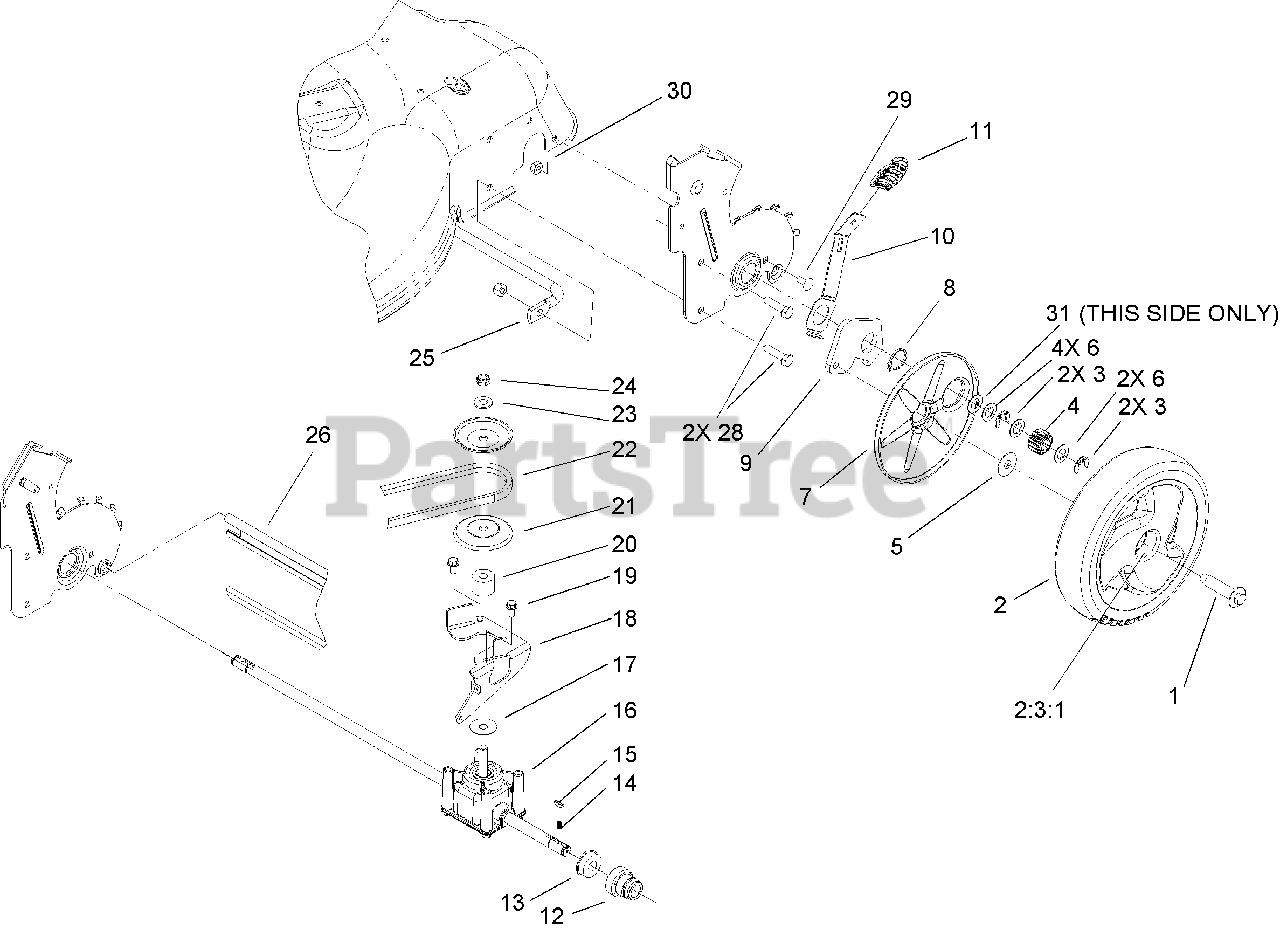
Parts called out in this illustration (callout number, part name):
1	BOLT-SHOULDER
2	WHEEL GEAR ASM, 8-INCH
3	KLIPRING-LOCKING
4	Gear-Pinion, 15t
5	WASHER-STEPPED
6	Washer-Thrust
7	COVER-WHEEL
8	RING-RETAINING
9	Arm-Pivot, Rear
10	Arm-Spring
11	KNOB-LEVER, HOC
12	RETAINER-BEARING, HOC
13	BEARING-BALL
14	SPRING-COMPRESSION
16	TRANSMISSION ASM
17	Washer-Shield
18	BRACKET-PIVOT, RWD
19	SCREW-HWH
21	PULLEY-HALF
23	WASHER-FLAT
24	NUT-LOCK, NI
25	BRACE-HOC PLATE
26	Shield-Trailing
28	SCREW-HH
29	SCREW-CARR
30	NUT-LOCK, NI
